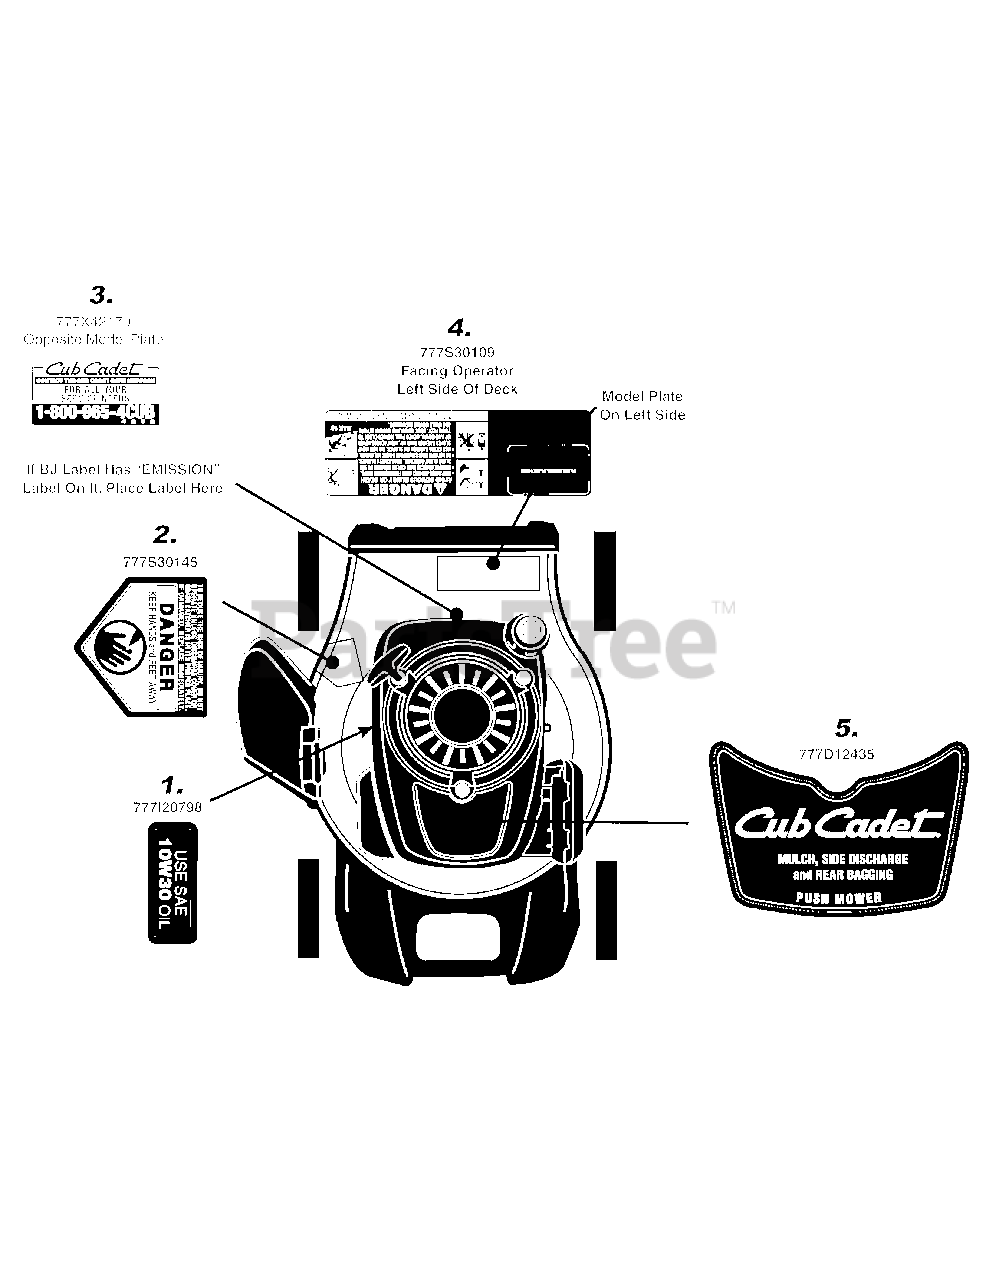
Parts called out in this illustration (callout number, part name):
1	LABEL-SHROUD
2	LABEL
3	LABEL-CUB HOTLINE
4	LABEL-MOWER DANGER
5	LABEL-ENG SHROUD
